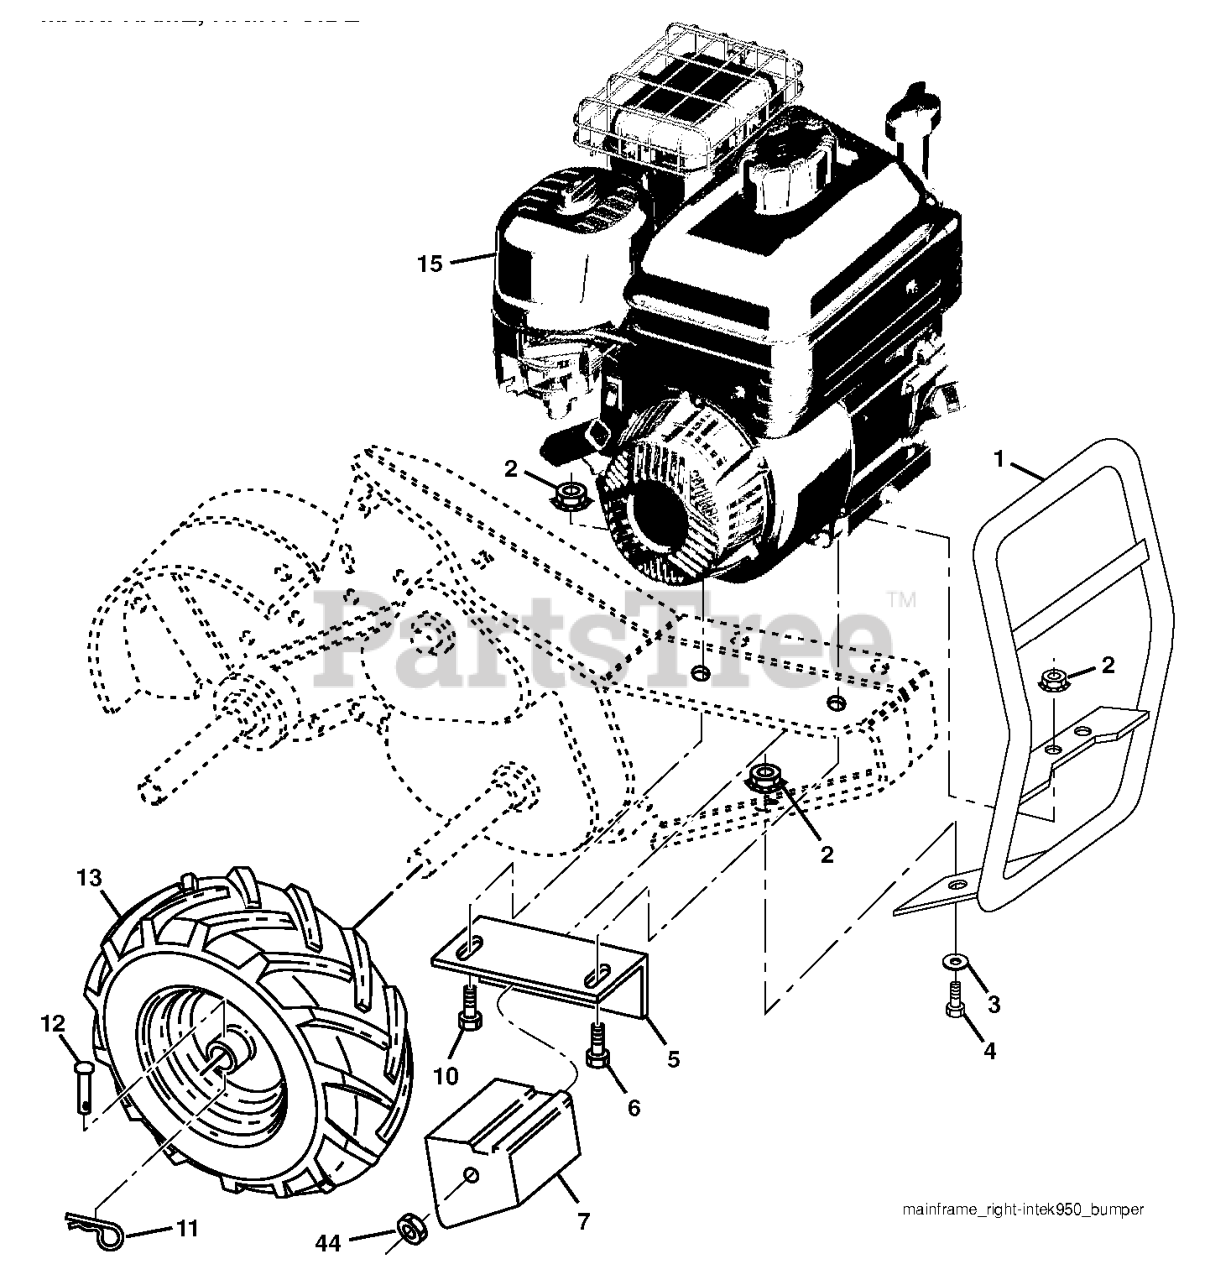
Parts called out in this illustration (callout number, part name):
1	BUMPER.ASM.TILLER.BLACK
2	LOCKNUT-FLANGE 5/16-18
3	WASHER
4	BOLT
5	BRACKET.REINFORCEMENT.RH.BLACK
6	BOLT, HEX 5/16-18X1-3/4
7	COUNTERWEIGHT.RH
10	BOLT
11	RETAINER M
12	RIVET
13	WHEEL.ASM.DRT.13X5-6.RT.SILVER
